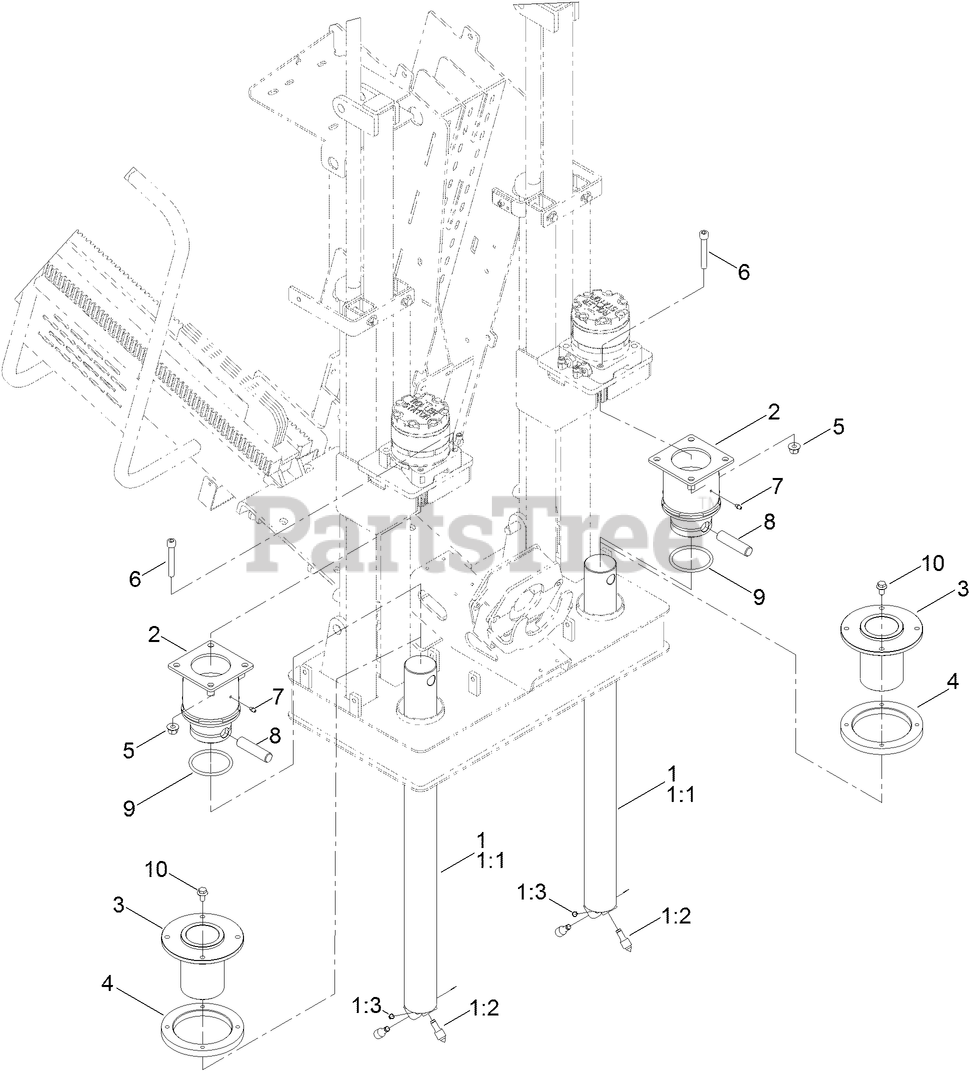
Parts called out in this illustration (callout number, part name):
1	HD ROCK STAKE ASM
1:1	STAKE-ROCK, HD
1:2	BIT-BULLET, MINI
1:3	RING-SNAP
2	COUPLER-STAKE DOWN
3	GUIDE-STAKE
4	RING-GUIDE
5	NUT-LOCK, HHF
6	SCREW-HSH
7	FITTING-GREASE
8	PIN-STAKE
9	O-RING
10	SCREW-HHF
